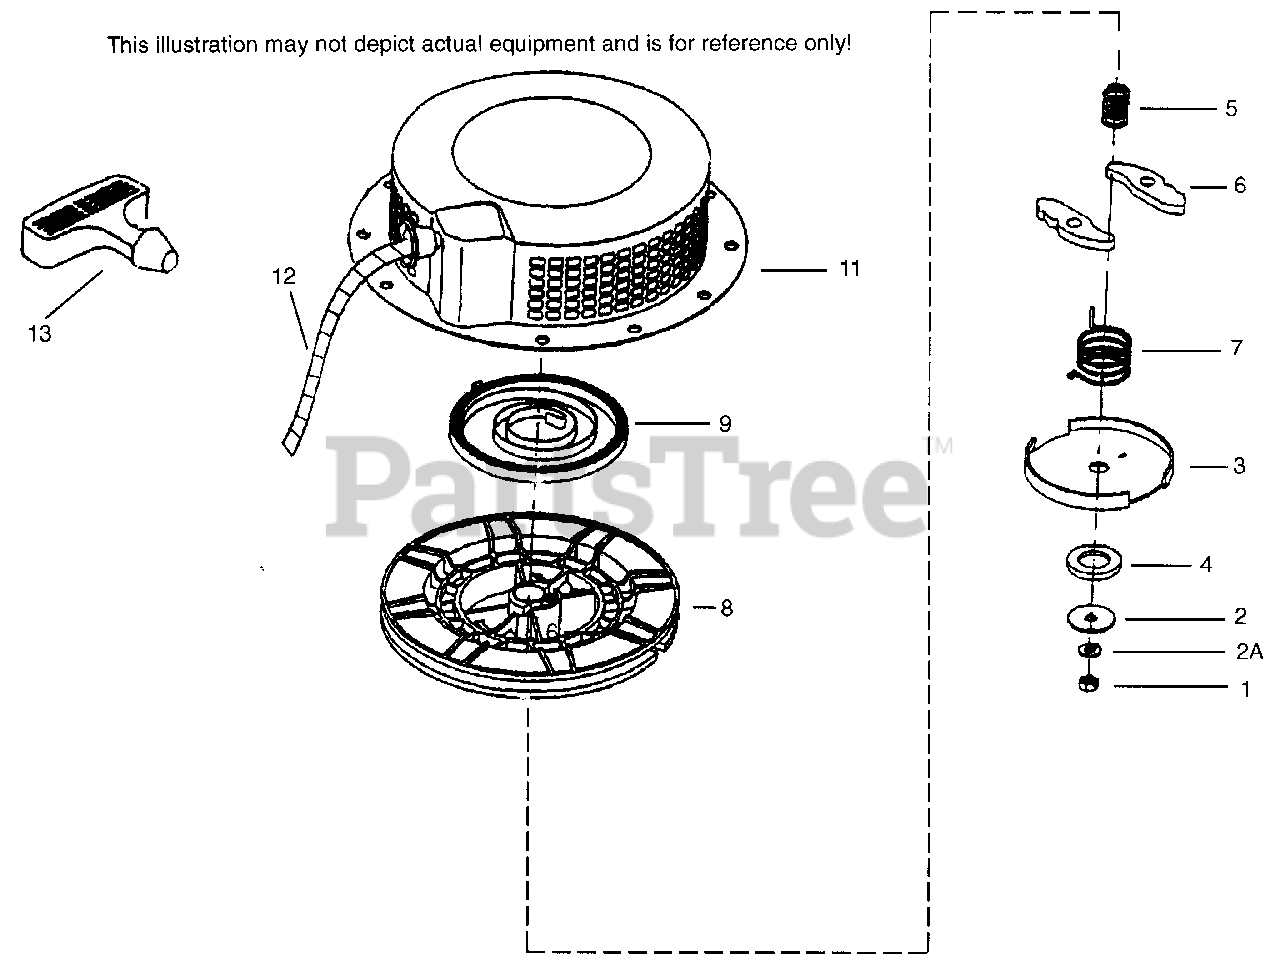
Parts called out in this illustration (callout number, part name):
1	Nut (Metric)
3	Starter Dog Retainer
5	Brake Spring
6	Starter Dog
7	Starter Dog Spring
9	Rewind Spring
11	Starter Housing Ass'y.
12	Starter Rope (52" & 3/16" dia.)
13	Starter Handle
